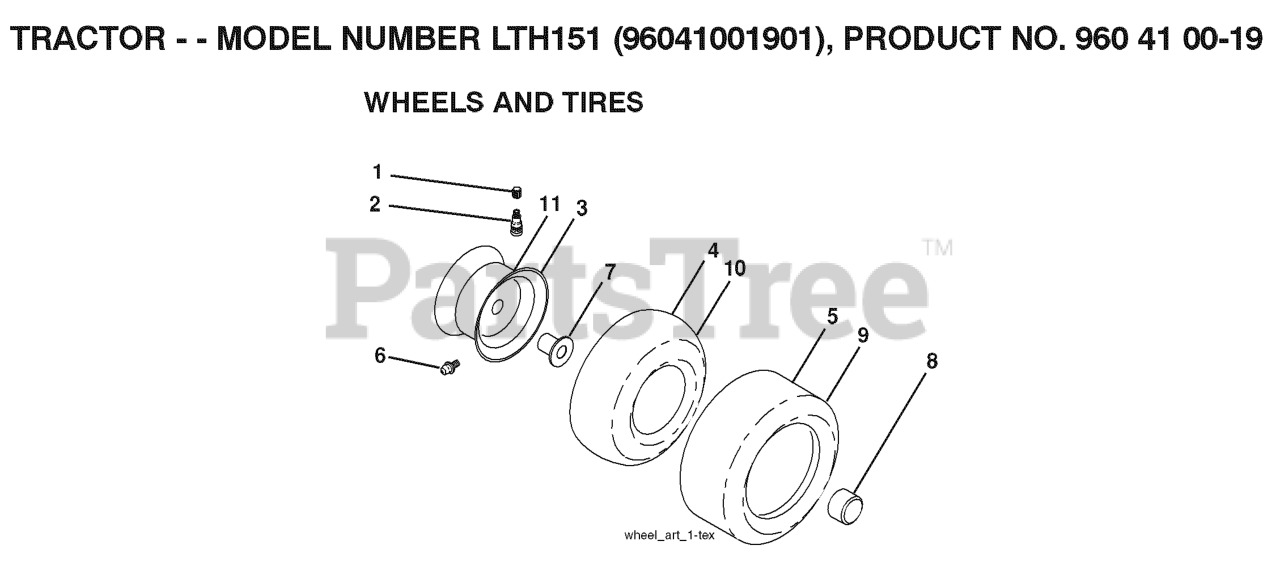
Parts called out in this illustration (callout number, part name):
2	VALVE STEM LT
3	RIM ASM 6" FRONT SILVER
4	TUBE.5.3/4.5/6
5	TIRE HEAVY DUTY
6	FITTING LT
7	BEARING T
8	CAP, AXLE BLK
9	TIRE HEAVY DUTY
10	TUBE
11	RIM ASM 8" REAR SILVER
